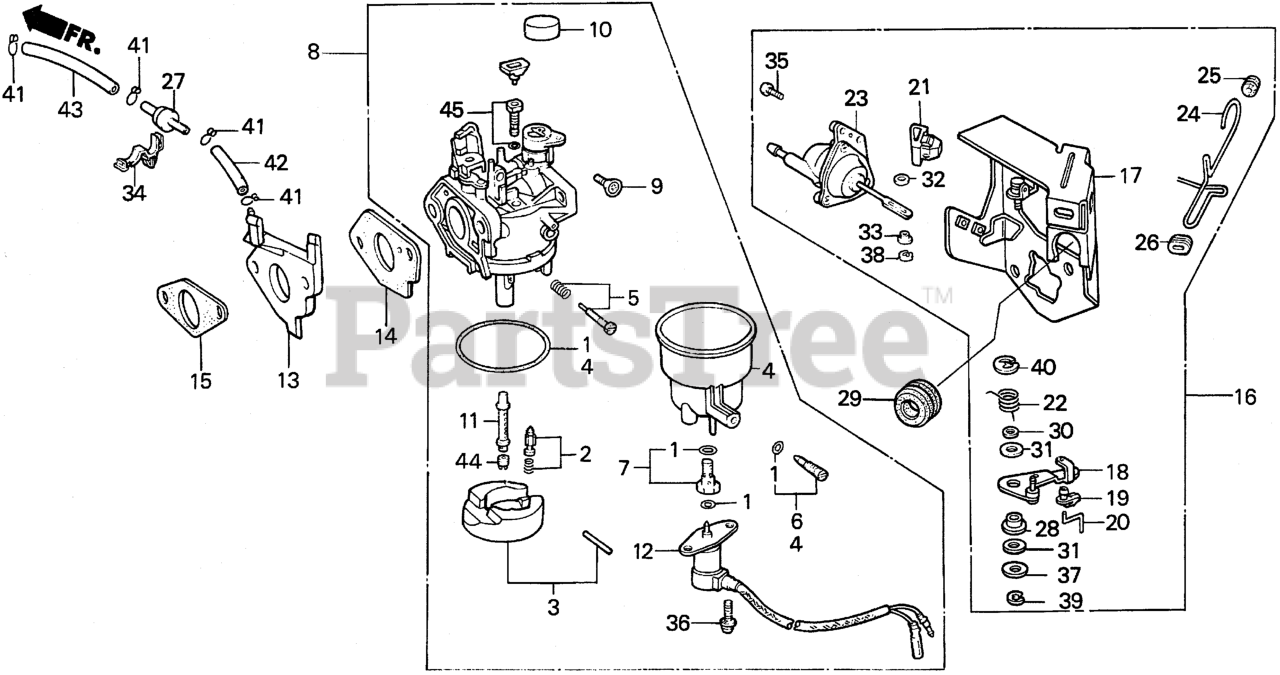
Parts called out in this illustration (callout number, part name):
1	GASKET SET
2	VALVE SET, FLOAT
3	FLOAT SET
4	CHAMBER SET, FLOAT
5	SCREW SET, PILOT
6	SCREW SET, DRAIN (ADVENTURE GREEN) (CARBURETOR NO.)
7	SCREW SET B
8	CARBURETOR ASSY. (BE20A C)
8	CARBURETOR ASSY. (BE20A D)
9	SCREW, THROTTLE STOP
10	CAP, CHOKE LEVER DUST
11	NOZZLE, MAIN (NOT AVAILABLE)
12	VALVE, SOLENOID (NOT AVAILABLE)
13	INSULATOR, CARBURETOR
14	GASKET, CARBURETOR
15	GASKET, INSULATOR
16	STAY ASSY., MANUAL CHOKE
17	STAY, SOLENOID
18	LEVER, CHOKE
19	JOINT, ROD
20	ROD, CHOKE
21	STOPPER, CHOKE ROD
22	SPRING, MANUAL CHOKE
23	DIAPHRAGM ASSY.
24	ROD, CHOKE CONTROL
25	GROMMET, CHOKE ROD
26	GUIDE, CHOKE ROD
27	VALVE, DASHPOT CHECK
28	BUSH, ARM PIVOT
29	GROMMET, FENDER
30	WASHER, CHOKE LEVER
31	SEAL, CHOKE LEVER
32	WASHER, THRUST (2.7X8)
33	COLLAR, LEVER
34	CLIP, WIRE HARNESS
35	SCREW, PAN (5X12)
36	SCREW-WASHER (5X12)
37	WASHER, PLAIN (5MM)
38	E-RING (2MM)
39	E-RING (4MM)
40	E-RING (7MM)
41	CLIP, TUBE (B7)
42	BULK HOSE, VACUUM (3.5X8000) (3.5X130)
43	BULK HOSE, VACUUM (3.5X8000) (3.5X130)
44	JET, MAIN (#80)
44	JET, MAIN (#82)
44	JET, MAIN (#85)
45	JET SET, PILOT (#35)
